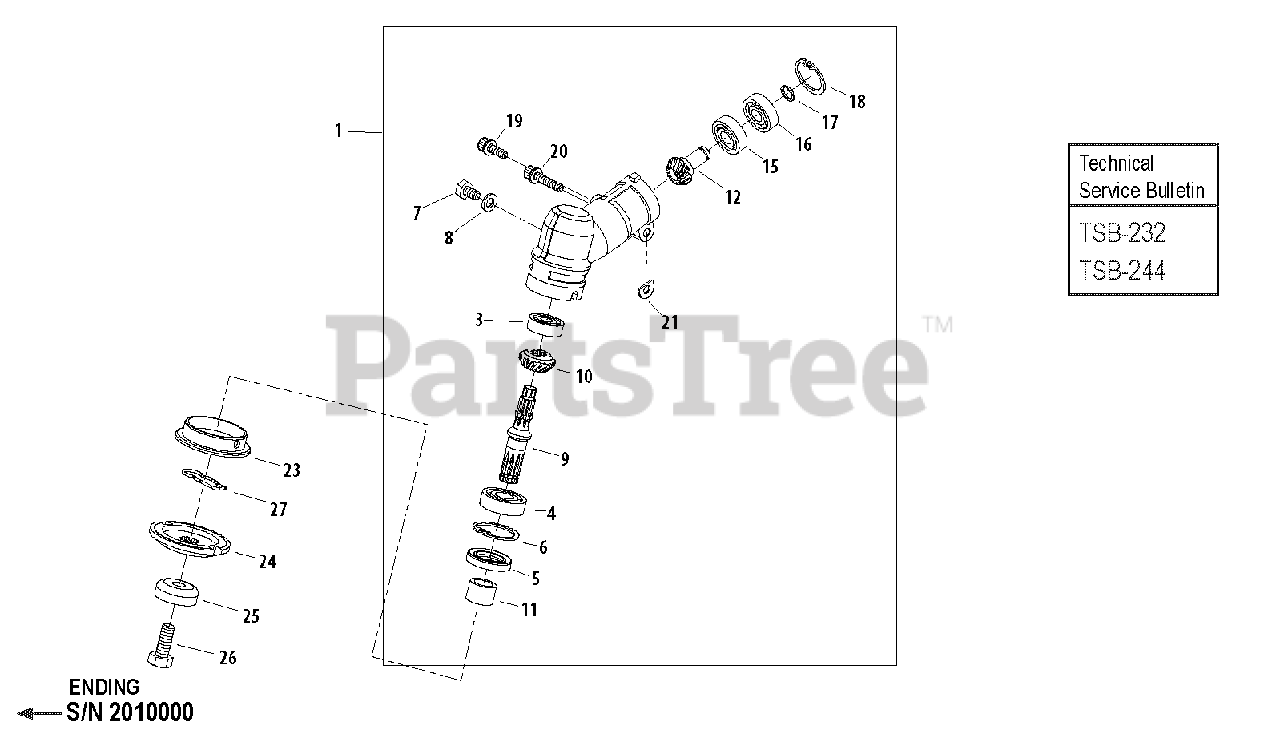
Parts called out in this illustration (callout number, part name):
1	GEAR CASE ASSY
3	BEARING, BALL - 608DDU
4	BEARING, BALL - 6001
5	SEAL, OIL
6	RING, RETAINING - 28
7	BOLT - 6X10
8	WASHER - 6
9	GEAR - SHAFT
10	GEAR SET
11	COLLAR
12	GEAR SET
15	BEARING, BALL - 609
16	BEARING, BALL - 609ZZ
17	RING, RETAINING
18	RING, RETAINING - 24
19	SCREW - 5X16
20	SCREW - 5X25
21	SHIM
23	HOLDER - A
24	ADAPTOR, BLADE - LOWER
25	GUARD
26	BOLT - 8 -- LEFT HAND
27	CLIP
